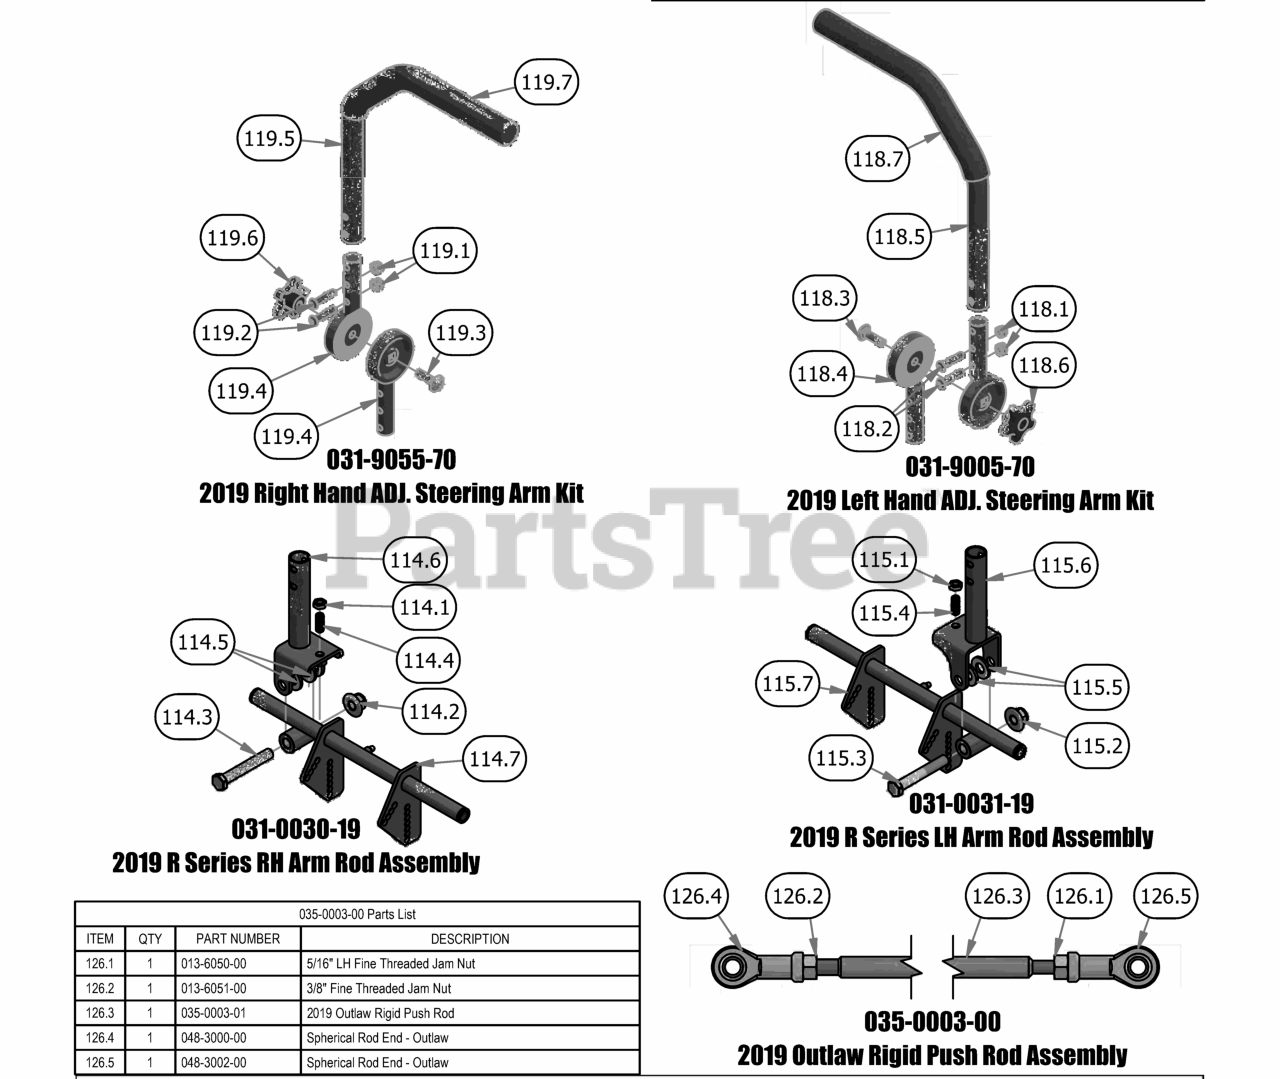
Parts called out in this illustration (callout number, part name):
114.1	3/8-16 Half Jam Nut
114.2	1/2-13 Nylon Flange Nut
114.3	1/2-13 x 3.25 GR 5 Hex Bolt Zinc
114.4	3/8-16 x 1 Set Socket Set Screw Cup Point
114.5	.505 Nylon Spacer
114.6	Drive Arm Pivot
114.7	2019 Drive Arm Actuator right
115.1	3/8-16 Half Jam Nut
115.2	1/2-13 Nylon Flange Nut
115.3	1/2-13 x 3.25 GR 5 Hex Bolt Zinc
115.4	3/8-16 x 1 Set Socket Set Screw Cup Point
115.5	.505 Nylon Spacer
115.6	Drive Arm Pivot
115.7	2019 Drive Arm Actuator left
118.1	5/16-18 Nylock Insert Locknut
118.2	5/16-18 BHCS, TORX DRIVE
118.3	3/8" x 1 1/4" Carriage Bolt
118.4	2019 Steering Arm Adjuster Casting
118.5	2019 Steering Arm Grip
118.6	Black Knob for Adjustable Steering Arm
118.7	Black Steering Arm Grip
119.1	5/16-18 Nylock Insert Locknut
119.2	5/16-18 BHCS, TORX DRIVE
119.3	3/8" x 1 1/4" Carriage Bolt
119.4	2019 Steering Arm Adjuster Casting
119.5	2019 Steering Arm Grip
119.6	Black Knob for Adjustable Steering Arm
119.7	Black Steering Arm Grip
126.1	5/16" LH Fine Threaded Jam Nut
126.2	3/8" Fine Threaded Jam Nut
126.3	2019 Outlaw Rigid Push Rod
126.4	Spherical Rod End - Outlaw
126.5	Spherical Rod End - Outlaw
